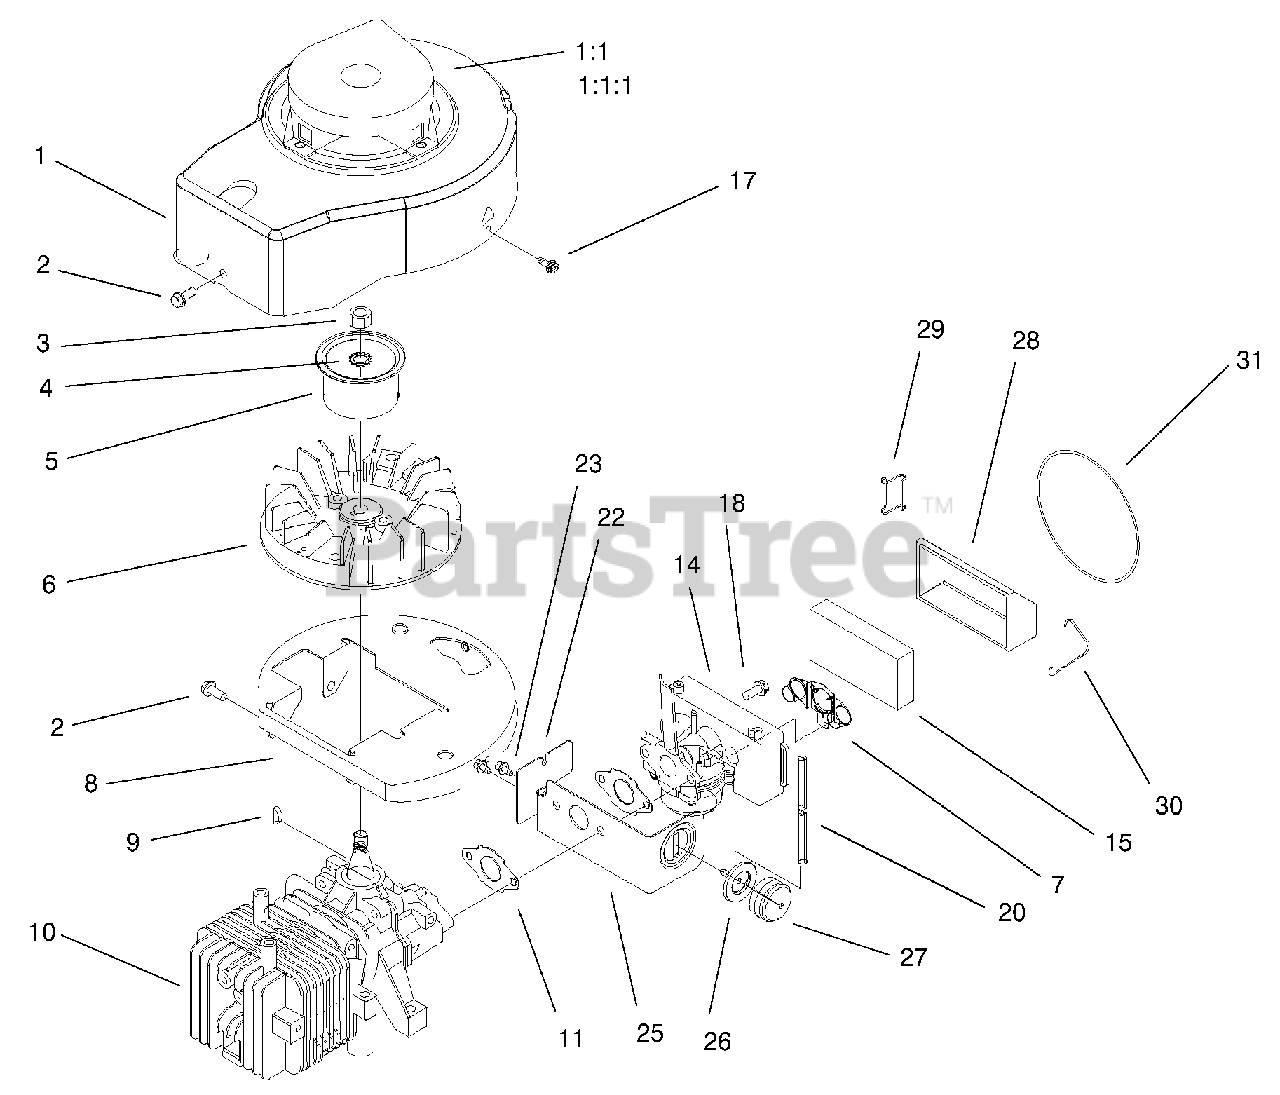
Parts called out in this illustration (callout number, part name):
1	Shroud/Start Ay
1:1	Recoil
2	Screw
4	Washer-Lock
5	Hub Starter
6	Flywheel,Mach.
7	Shield-Fuel
8	Shroud Base
10	Short Block Asy.
11	Gasket,Carb.
14	Carburetor ASM (Service)
15	Element Air/F
20	Hose-Primer
22	Shield-Gov.
25	Shield Primer Mounting
26	Body-Primer
27	Bulb-Primer
28	Cover-Air Filter
29	Hook Cover
30	Retainer Cover
31	O-Ring Cover
